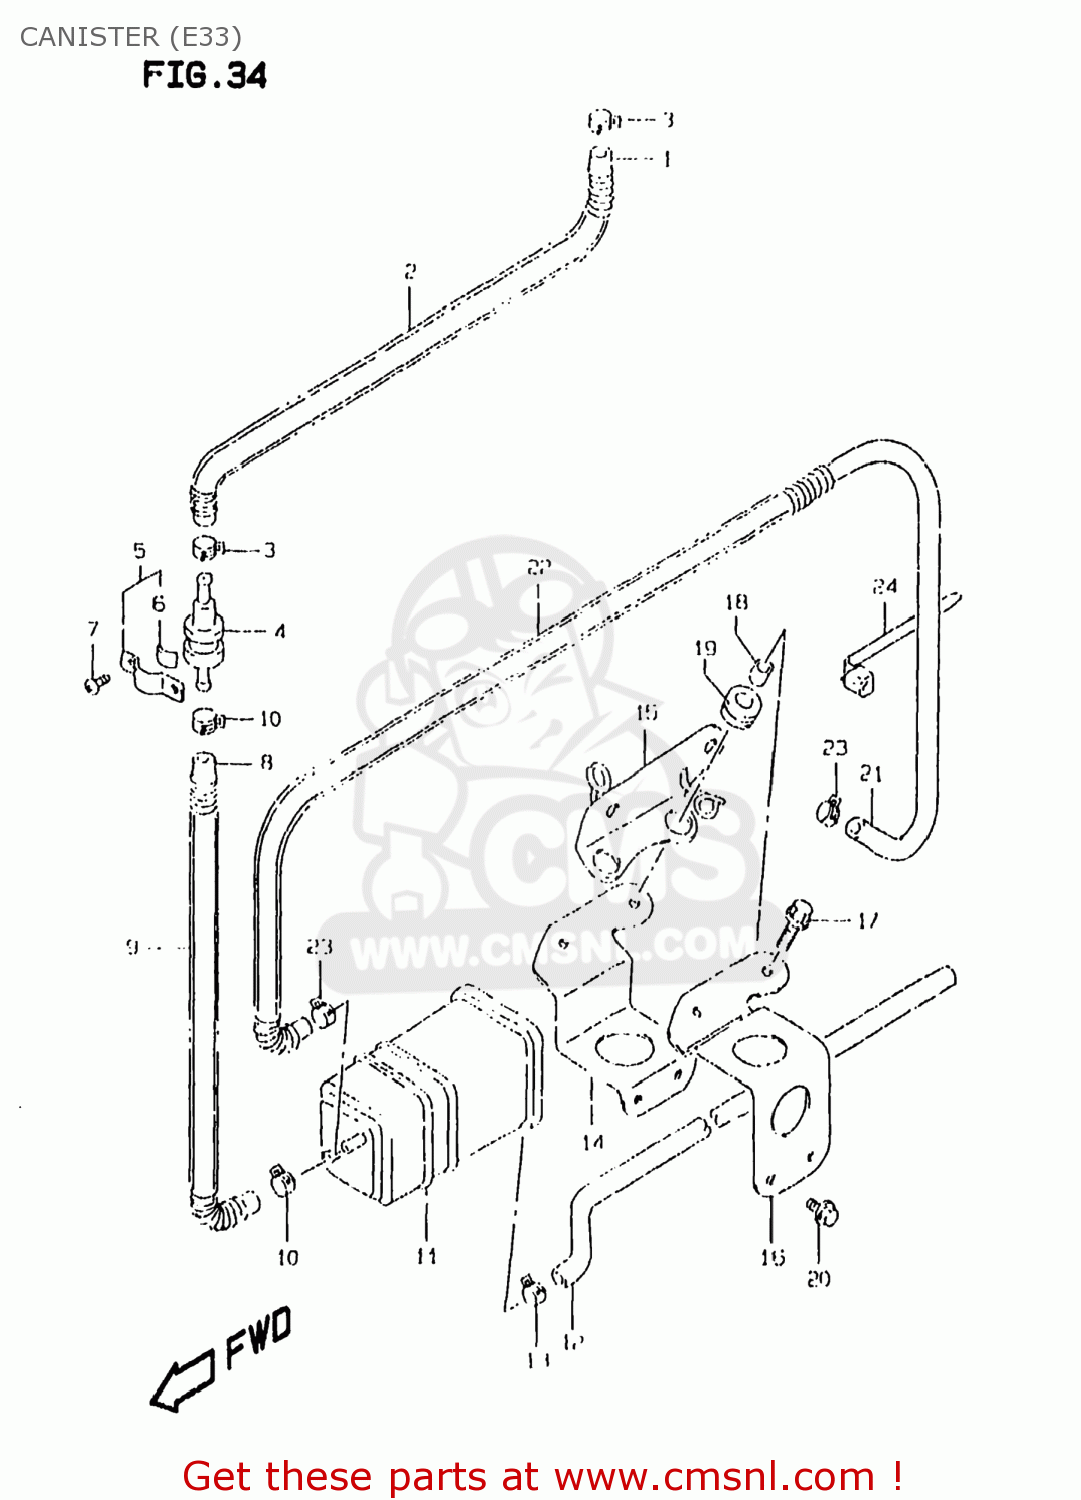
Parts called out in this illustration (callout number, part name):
1	HOSE (5.4X11.4X790)
2	SPRING
3	CLIP
4	VALVE,FUEL TANK BREATHER
5	PLATE,FUEL TANK BREATHER NO.2
6	CUSHION
7	SCREW
8	HOSE
9	SPRING
10	CLIP
11	CANISTER ASSY,CHARCOAL
12	HOSE,CANISTER PURGE AIR
13	CLIP
14	PLATE COMP,CANISTER,LOWER
15	PLATE COMP,CANISTER
16	PLATE,CANISTER,UPPER
17	BOLT(6X23)
18	SPACER(6.5X10X9.4)
19	CUSHION
20	BOLT
21	HOSE (5.4X11.4X790)
22	SPRING
23	CLIP
24	CLAMP(L:125)
